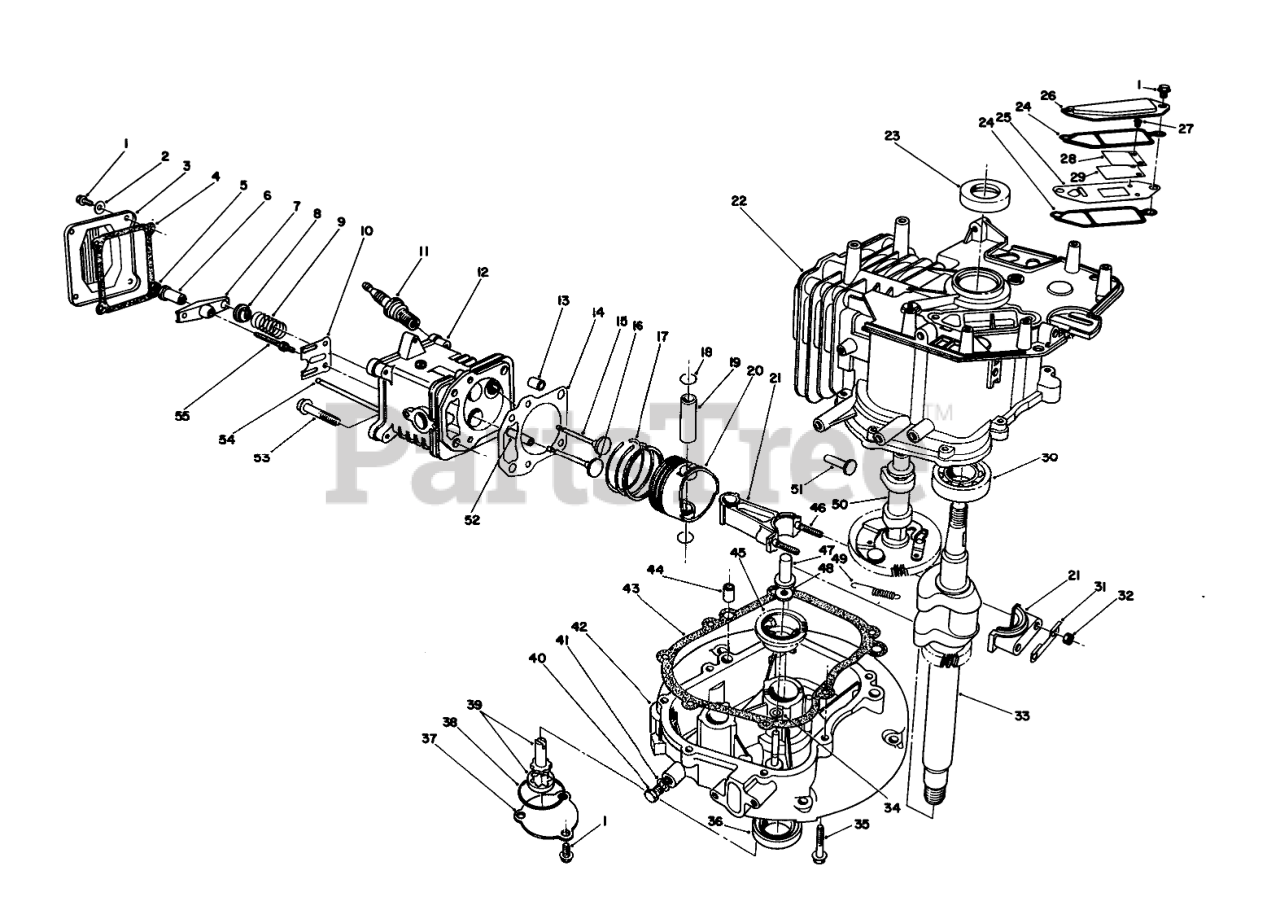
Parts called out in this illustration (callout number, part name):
2	WASHER
3	COVER
4	GASKET
6	PIVOT
8	RETAINER
9	SPRING
10	GUIDE
11	SPARK PLUG
12	Head-Cylinder (Incl. Ref. #52)
14	GASKET
15	VALVE-EXHAUST
16	VALVE-INTAKE
17	RING SET
18	CIRCLIP
20	PISTON
21	Connecting Rod Assembly (Incl. Ref. #31, 32 & 46)
22	Block-Engine (Incl. Ref. #23 & 30)
24	GASKET
25	Plate-Breather
26	COVER
27	Screw-Reed Valve
28	Retainer-Reed Valve
29	Valve-Reed
30	BEARING
31	Plate-Lock
33	CRANKSHAFT
34	WASHER
37	COVER
38	O-RING
39	OIL PUMP
40	OIL DRAIN PLUG
41	GASKET
42	Crankcase
43	GASKET
45	GOVERNOR FLYWEIGHT ASM
47	PLUNGER
48	WASHER
49	SPRING
50	Camshaft Assembly (Incl. Ref. #49)
51	TAPPET
52	GUIDE
